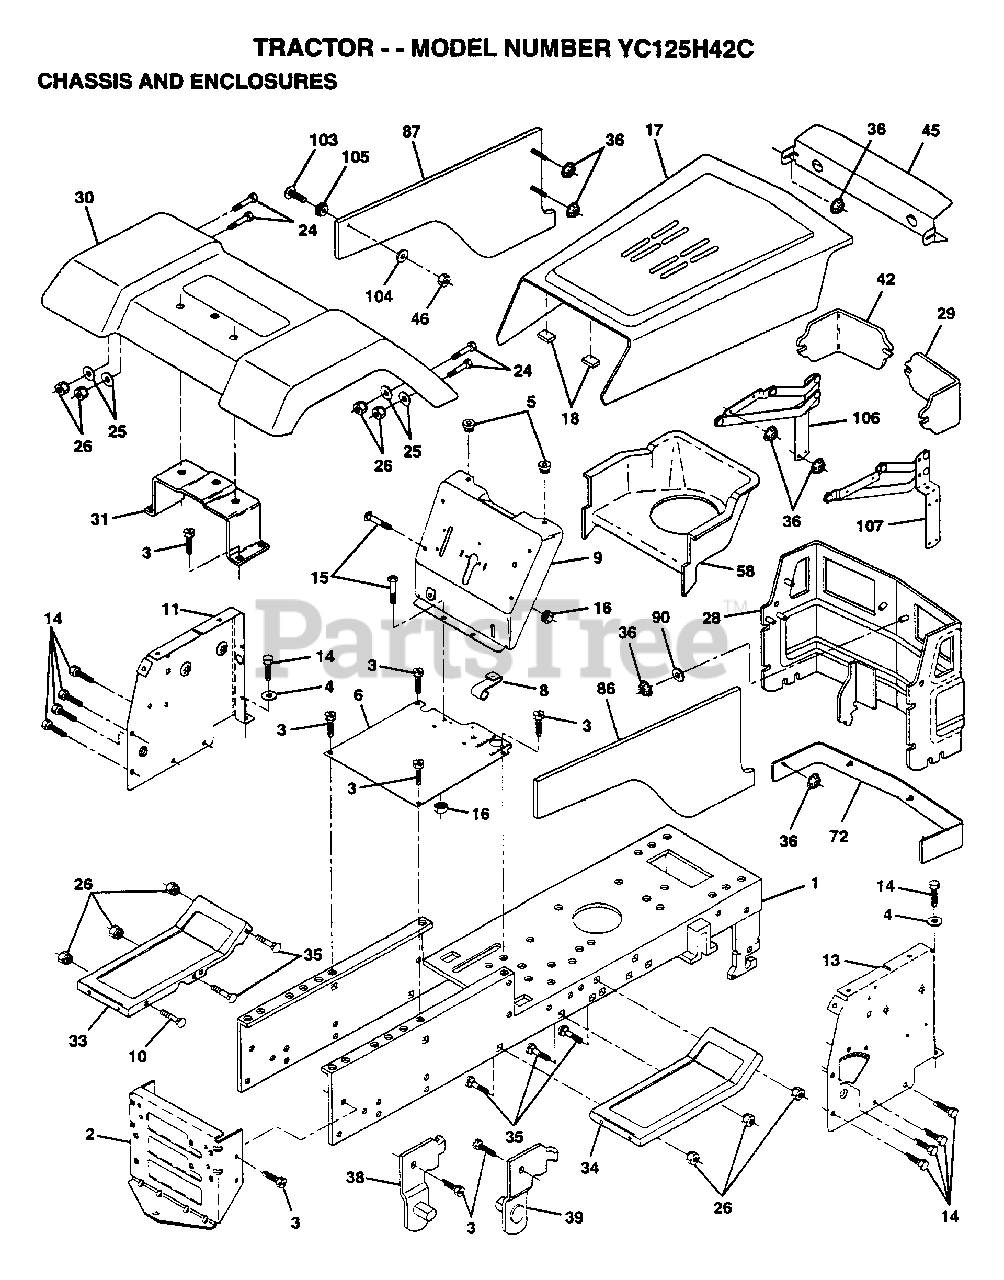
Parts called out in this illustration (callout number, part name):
1	CHASSIS.WLD.11GA
3	SCREW
4	WASHER
8	"CLIP,INSULATOR"
9	DASH.SLKSC.LT.1PC
11	PANEL.DASH.LH.
14	SCREW LT
15	SCREW
24	BOLT
25	WASHER
26	NUT
31	BRKT FENDER
33	FOOTREST.LH.LT/GT
34	FOOTREST.RH.LT/GT
35	BOLT
36	PAL NUT LT
38	BRACKET ASM LH
39	BRACKET ASM RH
46	RETAINER
58	"DUCT, INTAKE T"
72	STRAP ASM GRILL
86	SIDE PANEL ASM RH
87	SIDE PANEL ASM LH
90	WASHER PM
103	"SCREW,SPECIAL"
105	"GROMMET,PLASTIC"
106	"HINGE,HOOD,LH T"
107	"HINGE,HOOD,RH T"
